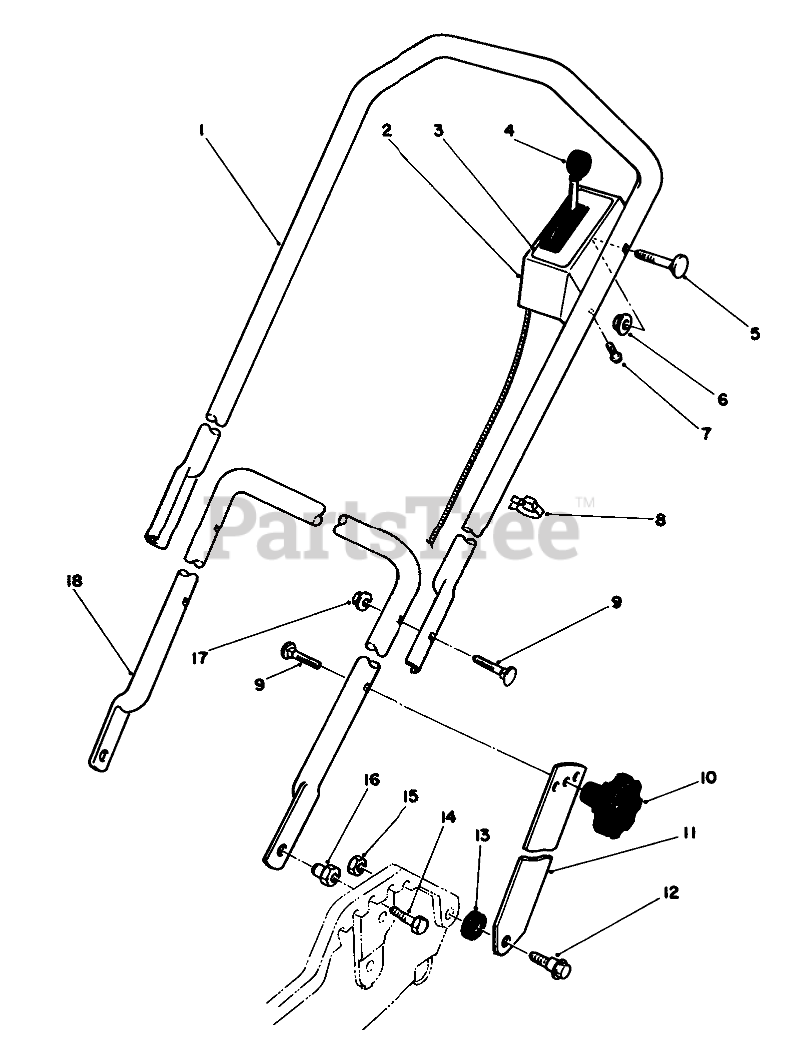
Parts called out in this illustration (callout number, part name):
1	UPPER HANDLE
2	Cover-Control (Incl. Ref. #3)
3	Decal-Control Cover
4	THROTTLE CONT-SERVICE
5	HANDLE SCREW
6	NUT-LOCK, HHF
7	SCREW-HWHTF
9	SCREW
11	Handle Latch
12	SCREW-SHOULDER
13	SPACER
14	SCREW-HH
15	NUT-LOCK, NI
16	HANDLE PIVOT NUT
17	NUT-LOCK, NI
18	LOWER HANDLE
